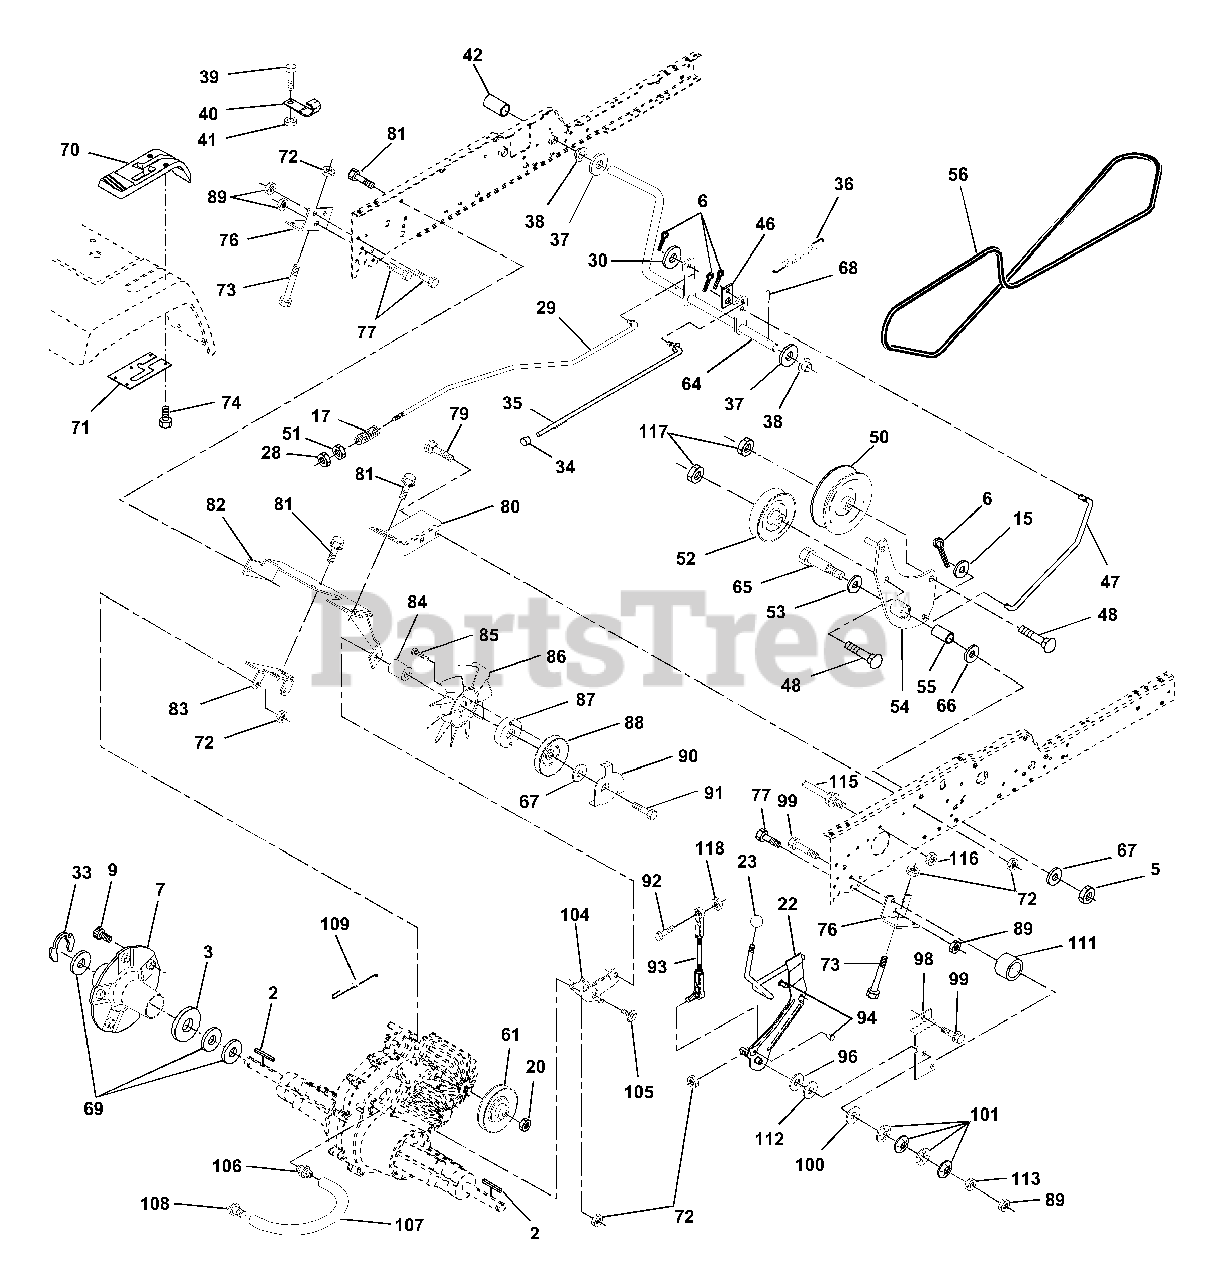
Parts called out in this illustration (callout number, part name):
2	Key 1/4 x 2.5
3	Washer Thrust Axle Harden
5	Nut Crownlock 3/8-16
6	Pin Cotter 1/8 x 3/4
7	Wheel Hub Asm.
9	Bolt Hub
15	Washer 13/32 x 13/16 x 16 Ga.
17	Spring Rod Brake
20	Nut Hex Jam Toplock 1/2-20
22	Shaft Arm Asm
23	Knob
28	Nut, Hex Jam 3/8-16
29	Brake Rod
30	Washer 13/32 x 1 x 14Ga
33	Ring E
34	Cap Plunger
35	Rod Parking Brake
36	Spring Extension
37	Washer 25/32 x 1-1/4 x 16 Ga.
38	Nyliner
39	Screw Fin #10-24 x 1
40	Actuator Interlock Switch
41	Nut Toplock #10-24 Unc
42	Cover Pedal
46	Retainer Spring
47	Clutch Rod
48	Bolt Carriage 3/8-16 x 1-1/2 Gr. 5
50	Pulley Idler Flat
51	Nut, Crownlock 3/8-16
52	Pulley Idler Grooved
53	Washer Hartdened
54	Arm Asm Idler Clutch 98
55	Bearing, Idler
56	V-Belt
58	Screw 3/8-16 x 1-1/2
61	Pullery Transaxle
64	Shaft Asm Brake Parking Clutch
65	Bolt Shoulder
66	Washer Hardened
67	Washer 13/32 x 13/16 x 12 Ga
68	Pin Roll
69	Washer
70	Console Hydro Fender
71	Plate Console Shift
72	Locknut Hex W/Washer Insert
73	Bolt Hex Flghd 5/16-18 x 3 Gr. 5
74	Screw, Hex Wsh Hi-Lo 1/4-1/2
76	Bracket Transaxle
77	Bolt Fin Hex 7/16-14 x 1
79	Bolt Carriage 5/16-18 x 5/8
80	Bracket Torque RH
81	Screw 3/8-16 x 3/4
82	Bracket Mount Torque/Fan
83	Strap Torque Mid
84	Spacer
85	Screw #10-24 x 1-1/4
86	Fan 7" Hydro
87	Adapter Fan
88	Pully Idler V-Groove Flange
89	Nut, Crownlock 7/16-14
90	Keeper Belt
91	Screw Thdrol 3/8-16 x 2-3/4
92	Bolt Fin Hex 5/16-18 x 1.75
93	Link Shift Asm
94	Fastner Christmas Tree
96	Washer Nickel Plated
98	Bracket Shift
99	Screw 3/8-16 x 1-1/2
100	Washer Compression
101	Washer Bellville
104	Bracket Idler
105	Screw Tap 1/4-20 x 1/2
106	O-Ring Asm Hydro Gear
107	Line Fuel Hydro 15" VGT Serv
108	Cap Asm Vent Hydro Gear
109	Spring Return Brake
111	Spacer Shift Lever VGTH
112	Washer Nylon High Temp
113	Nut Hex ASF 7/16-14 Unc
115	Keeper Belt T/A GND DR LR
116	Nut Lock Hex Flange 5/16-18
117	Nut Lock Flg. 3/8-16 Unc
